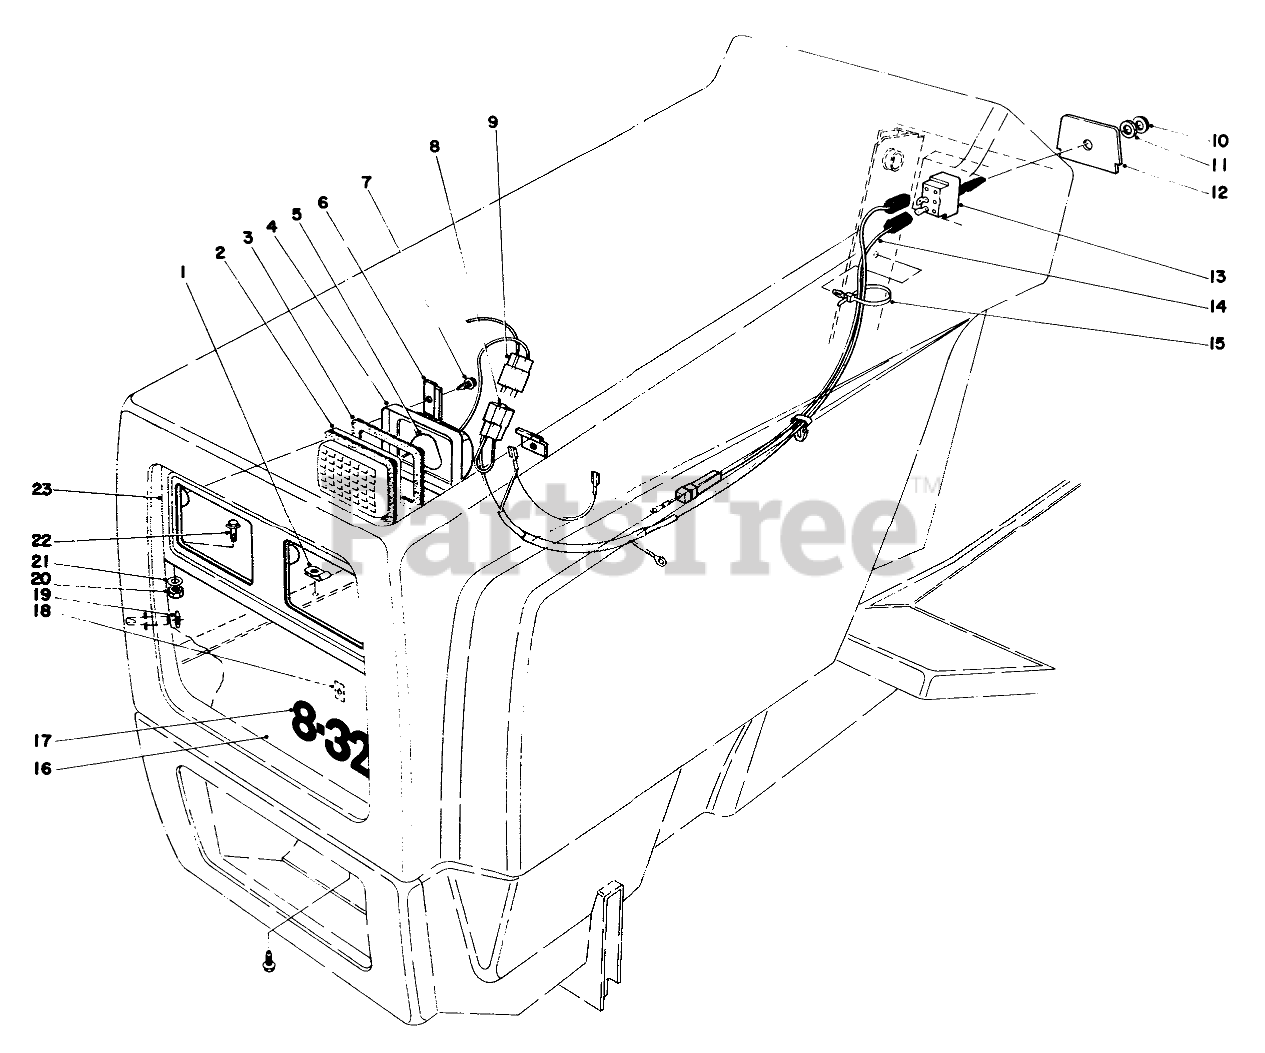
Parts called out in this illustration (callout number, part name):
1	CABLE CLAMP
2	Lens
3	Gasket Lens
4	Reflector
6	HEADLIGHT CLAMP
7	SCREW-HWHTF
8	CONNECTOR BODY
9	SOCKET
10	NUT-BULB
11	NUT-LOCK
12	DASH PANEL INSERT
13	LIGHT SWITCH
14	WIRE HARNESS
15	TIE-CABLE
16	Grille Headlight
17	Nameplate Grille
19	WASHER
20	NUT-LOCK, SIDE
21	WASHER-FLAT
22	SCREW-SHWH
23	HEADLIGHT PANEL B
